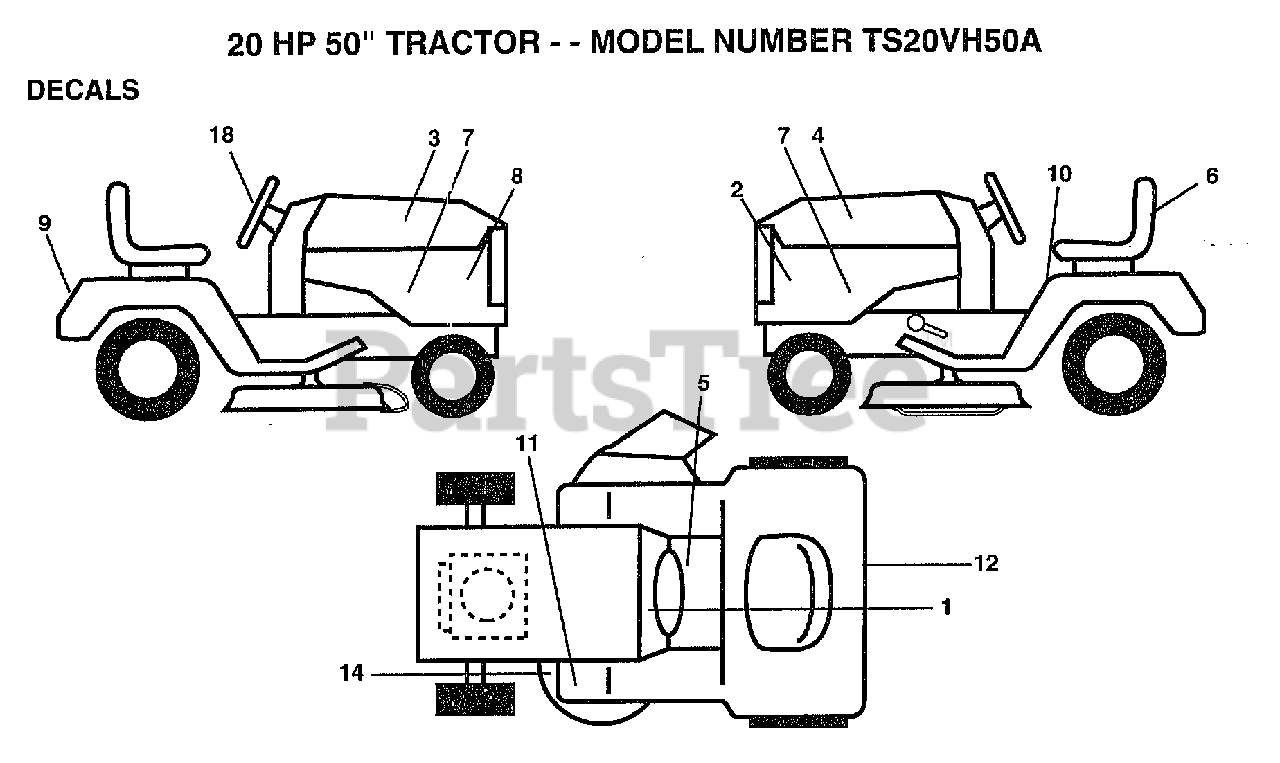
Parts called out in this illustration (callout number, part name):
1	DECAL.DASH.INST.
2	NAMEPLATE.HUSK.LG
3	DECAL.HD.RH.20/50
4	DECAL.HD.LH.20/50
5	DECAL BRAK PARK
6	DECAL.SEAT.AM.FLG
7	DECAL.PNL.SIDE.VA
8	DECAL SADLE HYDRO
9	DECAL.FEND.YT/GT
10	DECAL
12	DECAL D-BAR CNTRL
14	"DECAL.V.BELT.44"""
18	DECAL.INS.WHL.STG
